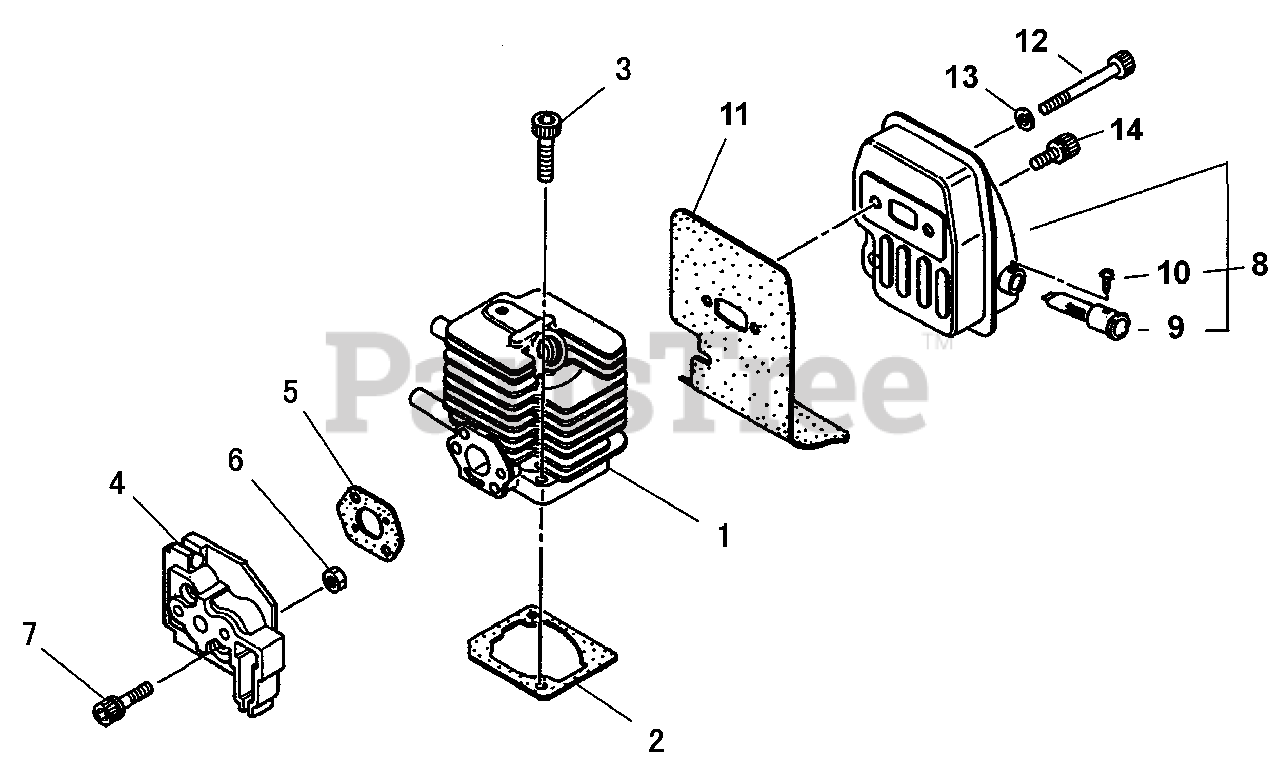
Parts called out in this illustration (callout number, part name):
1	CYLINDER
2	GASKET, CYLINDER
3	BOLT 5×25
4	INSULATOR
5	GASKET, INTAKE
6	NUT M5×6.3
7	BOLT M5×30
8	MUFFLER ASSY
9	SCREEN, SPARK ARRESTER
10	SCREW, TAPPING 3×6
11	HEAT SHIELD, EXHAUST
12	BOLT M5×50
13	WASHER, FLAT 5.5×10×0.8
14	BOLT 5×12
